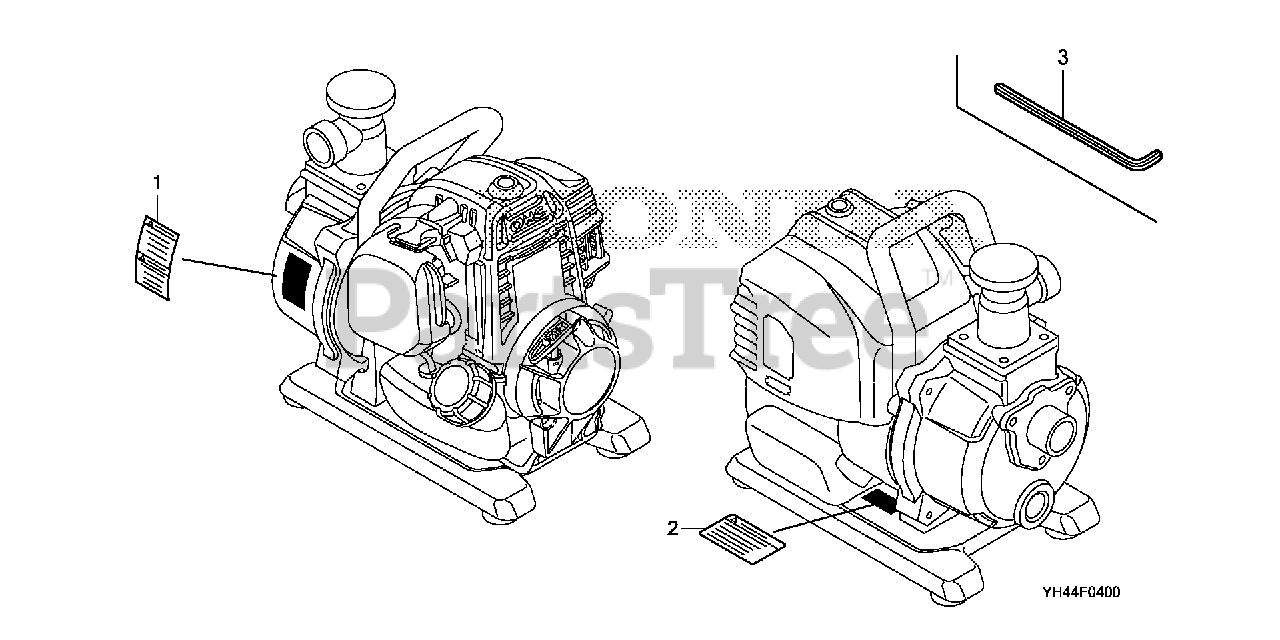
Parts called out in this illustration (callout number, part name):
1	MARK, CAUTION (PUMP)
2	LABEL, PUMP WARNING
3	WRENCH, HEX. (4MM)
